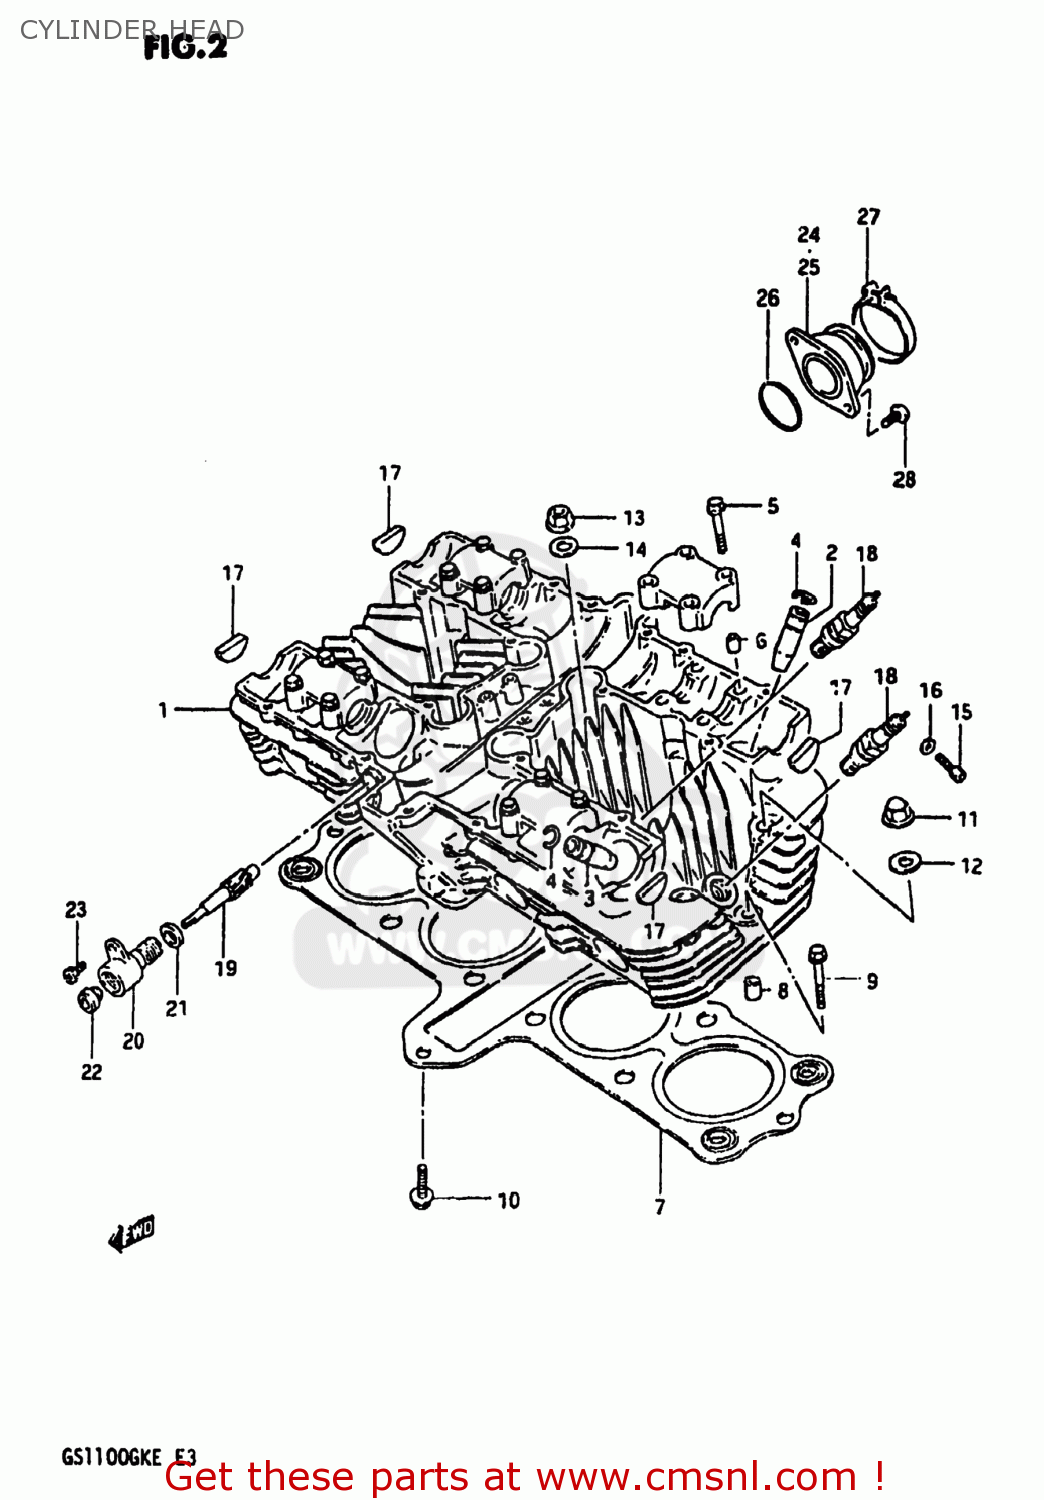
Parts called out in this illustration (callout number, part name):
1	HEAD ASSEMBLY,CYLINDER
2	GUIDE,INTAKE VALVE
3	GUIDE,EXHAUST VALVE
4	RING,SNAP
5	BOLT(6X39)
6	PIN(6.2X8X11)
7	GASKET,CYLINDER HEAD (NAS)
8	PIN
9	BOLT (6X45)
10	BOLT 6X30
11	NUT
12	GASKET(10.5X22X2) (NAS)
13	NUT
14	WASHER(10.5X22X2.3)
15	BOLT
16	GASKET(5.3X9.3X1.2) (NAS)
17	PLUG
18	PLUG,SPARK
19	GEAR,TACHOMETER DRIVEN
20	SLEEVE,TACHOMETER DRIVE GEAR
21	SEAL,TACHOMETER DRIVEN
22	SEAL,OIL(5X12X8)
23	SCREW(5X12)
24	PIPE,INTAKE,R
25	PIPE,INTAKE,L
26	O-RING (D:2.4 ID:39.7)
27	CLAMP
28	SCREW
